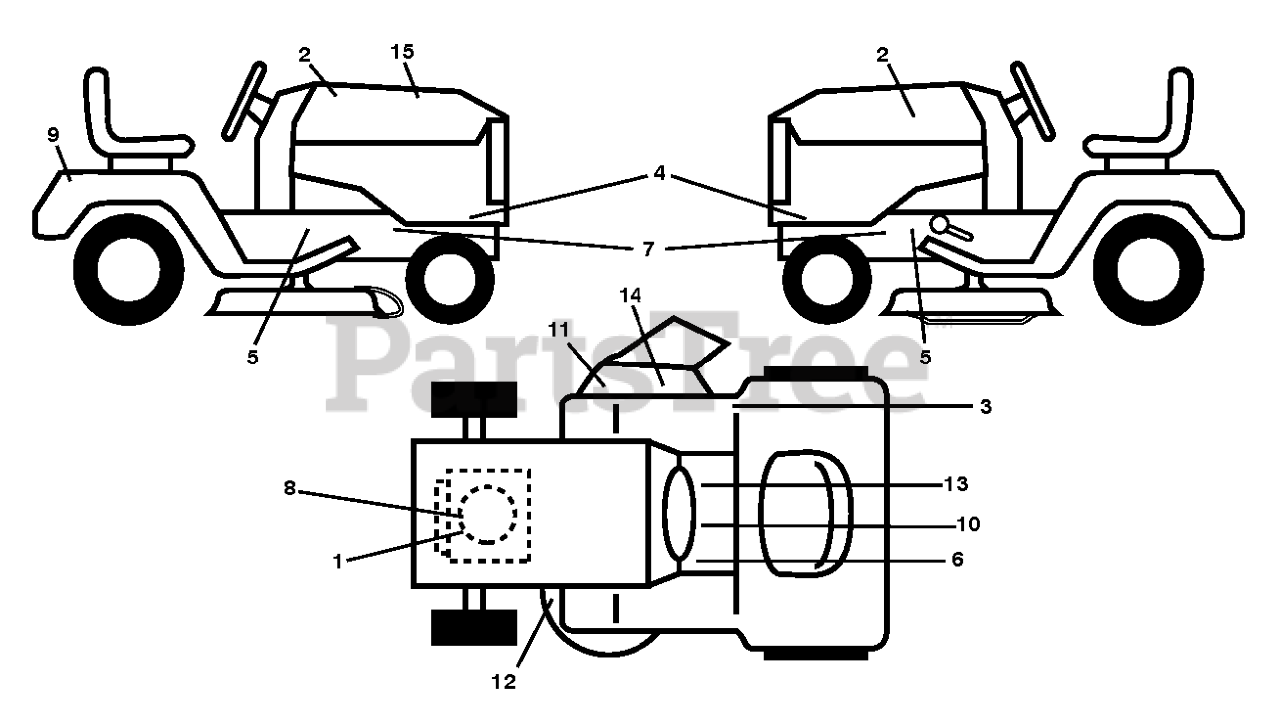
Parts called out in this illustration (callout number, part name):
1	DECAL.ENGINE.WARNING
2	DECAL.BADGE.170MM.TEXTLOGO.
3	DECAL.CERTIFICATION.6MIL.100D
5	DECAL.WARNING.SERVCE/FIRE
6	DECAL.FNDR.SDLE.BRAKE.CLUTCH.6
7	DECAL.CHASSIS.HOT.MUFFLER
8	DECAL
9	DECAL BTRY SYMBOLS
10	DECAL.READ.OWN.MAN.SYMBOL.LT
11	DECAL.WARN.DFLCTR/CTFNGR.SRD.
12	DECAL.V.BELT.30"
13	DECAL.PARKING.BRAKE.SADDLE.LT
14	DECAL, DECK DEFLECTOR, WARNING
15	DECAL DECAL.RPL.BSM21.PB.SRD.3
